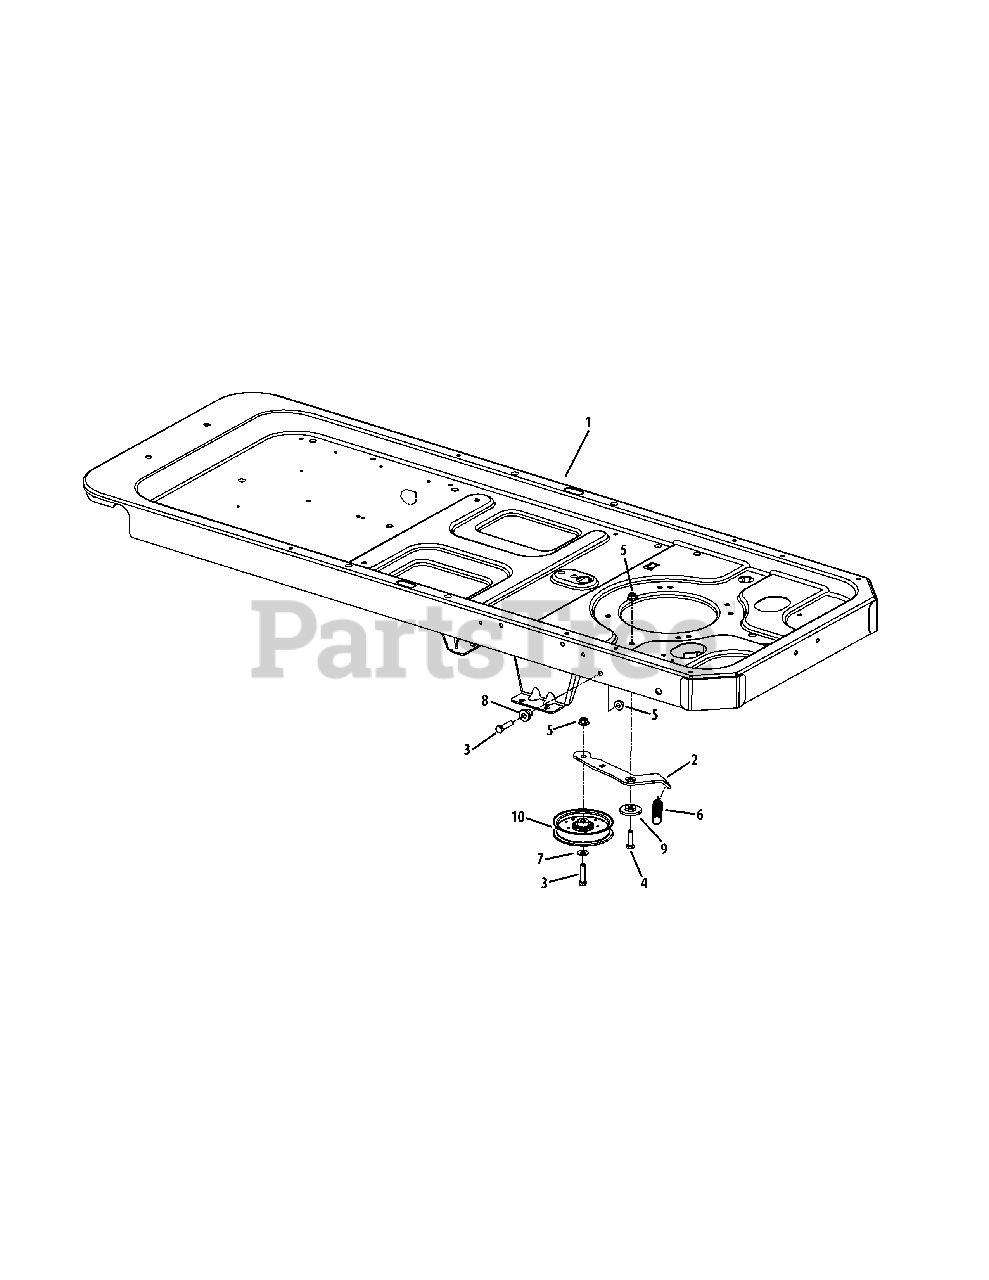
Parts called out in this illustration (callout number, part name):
1	Frame Assembly
3	Hex Screw, 3/8-16 x 1.5
4	Hex Screw, 3/8-16 x 1.25
5	Flange Nut, 3/8-16
6	Extension Spring, .75 x 5.06
7	Flat Washer, .406 x .875 x .059
8	Shoulder Spacer, .39 x 1.0 x .7
9	Shoulder Spacer, .884 x .19
10	Idler Pulley, 4.25 Dia.
